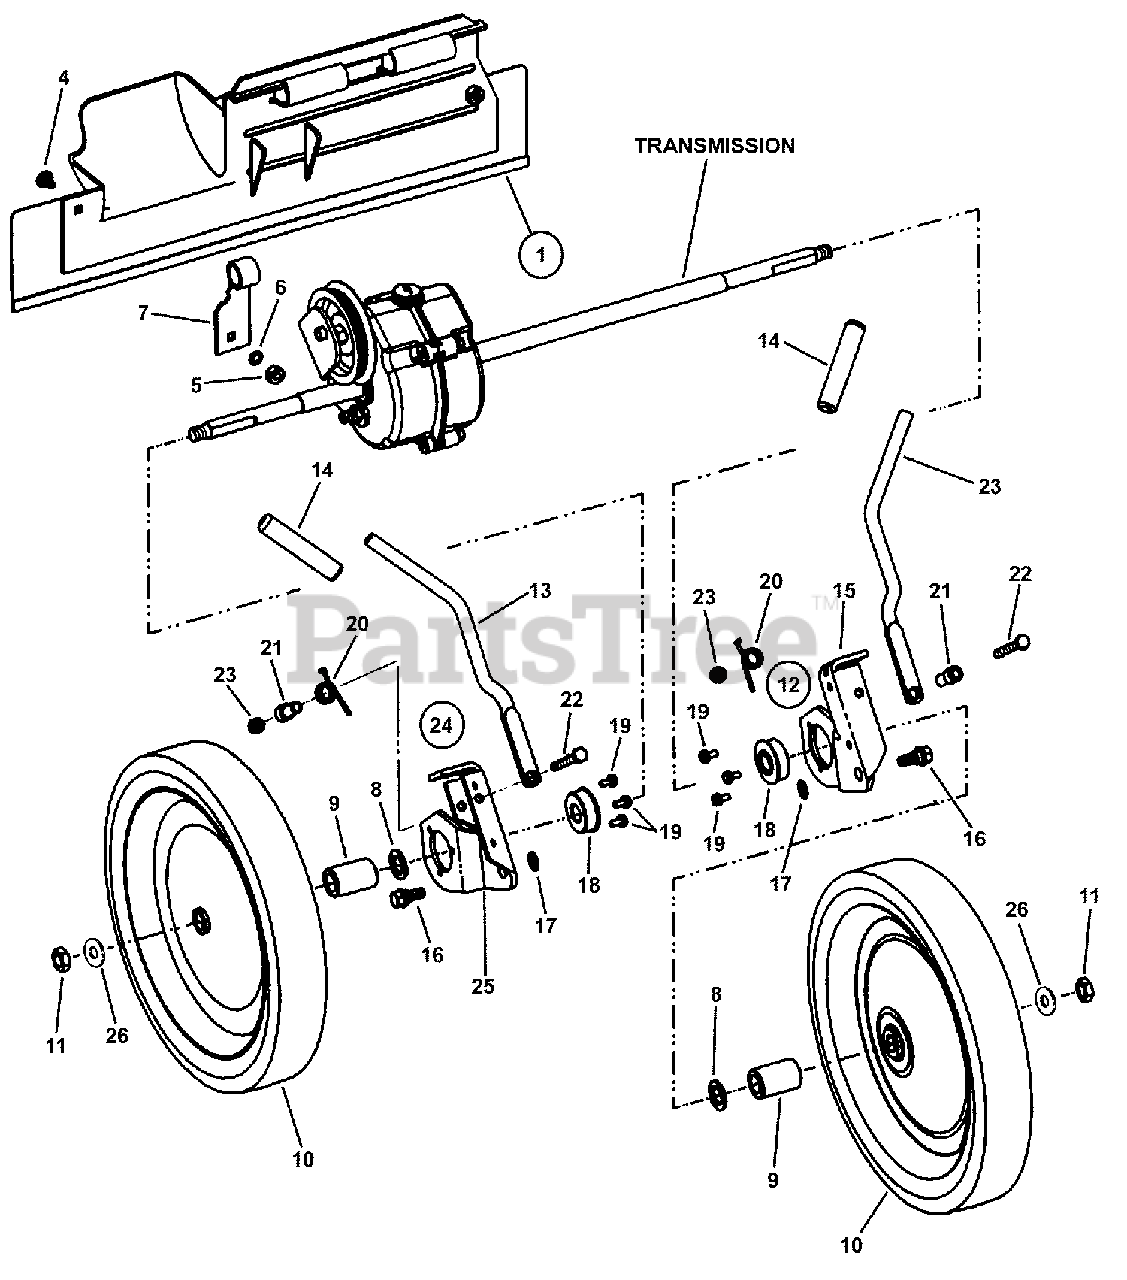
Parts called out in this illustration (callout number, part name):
1	ASSEMBLY, Debris Shield
4	BOLT, 1/4-20 x 1/2" Short Neck Carriage GR5
5	NUT, 1/4-20 Hex
6	WASHER, 1/4" Internal Tooth Lock
7	SUPPORT, Foot Guard
8	BUSHING, 5/8" Machine
9	SPACER, 5/8" I.D. x 1-1/2" long
10	WHEEL, 12" x 2.00 Diamond Tread
11	NUT, 7/16-20 Hex Center Lock Jam
12	ASSEMBLY, Left Wheel Arm
13	LEVER, Height Adjuster
14	GRIP, Shift Handle
15	ARM, Left
16	BOLT, 5/16-18 Hex Washer Face Shoulder
17	RETAINER, 5/16" Bolt
18	BEARING, 9/16"
19	SCREW, #10-32 x 3/8" Hex Washer Self-Tap
20	SPRING, Return
21	SPACER, Height Adjust
22	SCREW, 1/4-20 x 2" Hex Head Cap GR5
23	NUT, 1/4-20 Hex Nyloc
24	ASSEMBLY, Right Wheel Arm
25	ARM, Right
26	WASHER, 7/16" Flat
